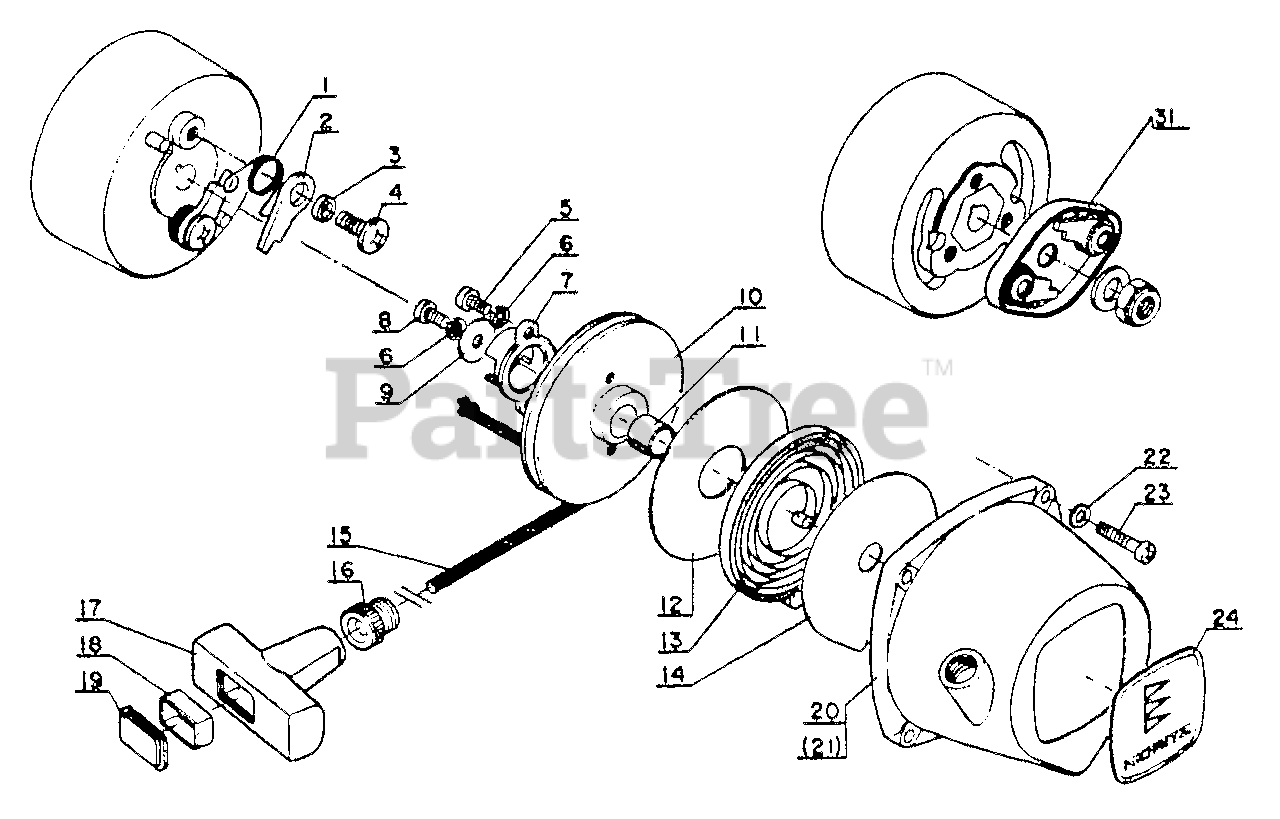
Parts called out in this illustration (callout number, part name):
1	SPRING, RETURN
2	PAWL, STARTER
3	SPACER 5.2×8×2.1
4	SCREW
5	SCREW - 4×8
6	WASHER, SPRING 4 MM
7	PAWL CATCHER
8	STARTER ASSY
8	SCREW - 4×6
9	WASHER 4.1×15.5×1T
10	REEL, ROPE
12	PLATE, STARTER
13	SPRING, RECOIL
14	PLATE, STARTER
15	ROPE, STARTER 3.5×850
16	GUIDE, ROPE
17	GRIP, STARTER
19	COVER, HANDLE
20	CASE, STARTER
22	WASHER 4 MM
23	SCREW - 4×20
24	PLATE, NAME
31	STARTER PAWL ASSY
